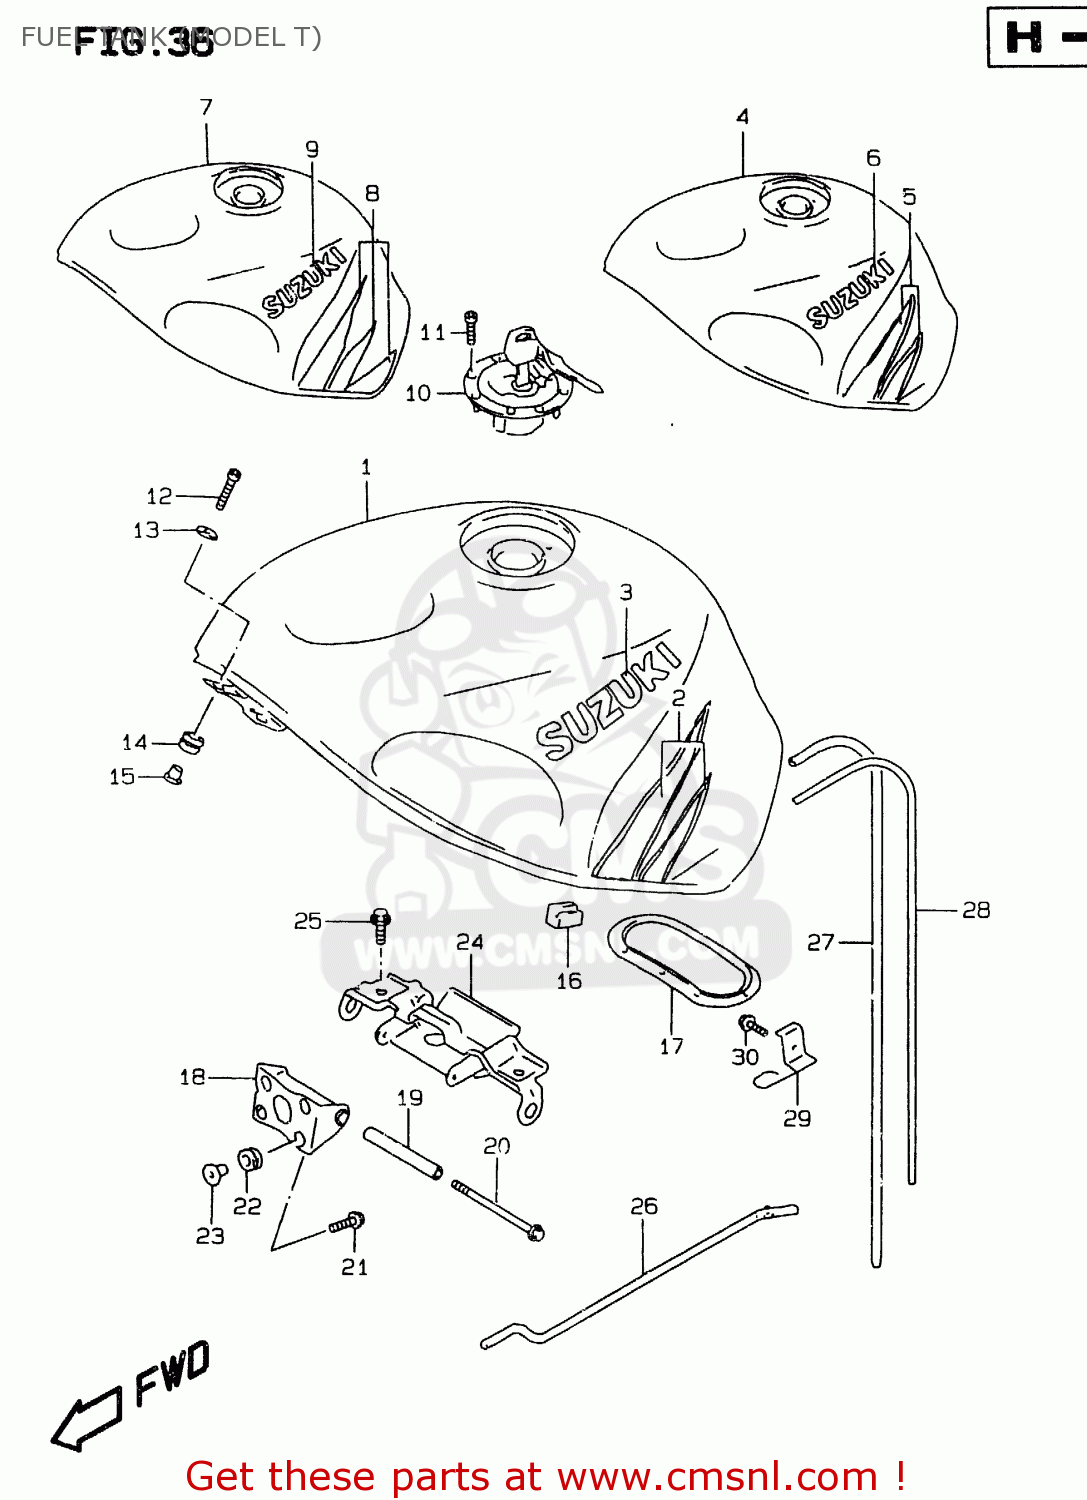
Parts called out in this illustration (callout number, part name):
1	TANK ASSY,FUEL
2	TAPE SET,FUEL TANK
3	EMBLEM,FUEL TANK
4	TANK ASSY,FUEL
5	TAPE SET,FUEL TANK
6	EMBLEM,FUEL TANK
7	TANK ASSY,FUEL
8	TAPE SET,FUEL TANK
9	EMBLEM,FUEL TANK
10	CAP SET,FUEL TANK
11	BOLT(5X20)
12	SCREW(6X25)
13	WASHER
14	CUSHION
15	WASHER
16	CUSHION COMP,FUEL TANK
17	PACKING,FUEL PUMP
18	BRACKET COMP,FUEL TANK
19	SPACER,FUEL TANK,REAR
20	BOLT
21	BOLT 6X20,WITH PLAIN WASHER
22	CUSHION
23	WASHER
24	BRACKET,FUEL TANK NO.2
25	BOLT
26	STAY,FUEL TANK
27	HOSE(5X8.2X600)
28	HOSE(7X10.2X600)
29	GUIDE COMP,DRAIN HOSE
30	BOLT
